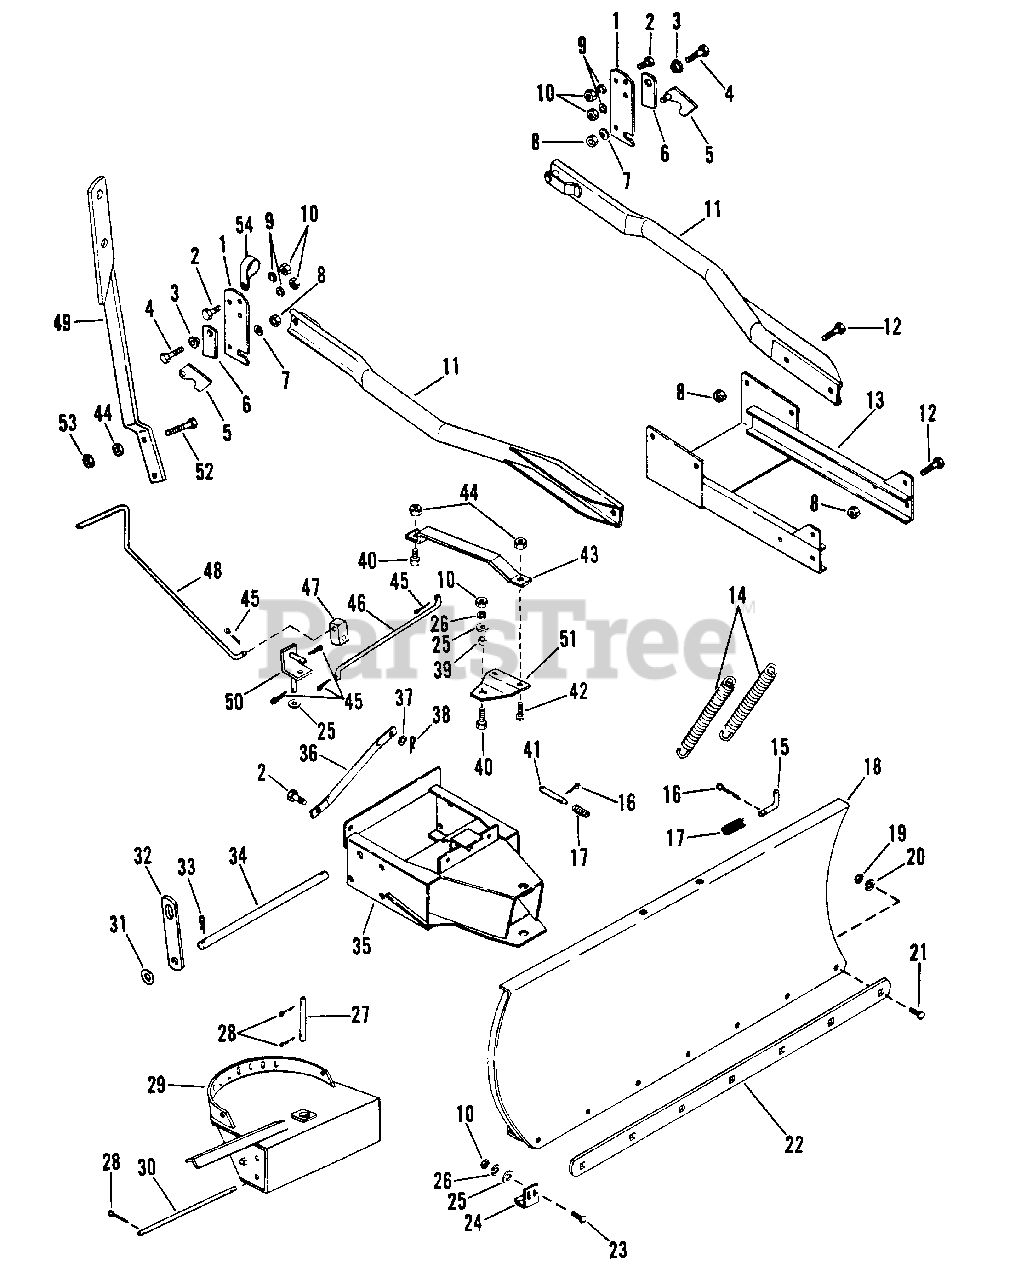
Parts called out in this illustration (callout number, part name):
1	Bracket, Rear Hanger
2	Bolt, Hex 3/8-16x1.00
3	Spacer
4	Bolt, Hex 3/8-16x1.50
5	Latch, R.H.
5	Latch, L.H.
6	Stop, Lock
7	Spring Washer
8	Nut, Lock 3/8-16
9	Washer, Lock 3/8 Reg.
10	Nut, Hex 3/8-16
11	Brace, Rear Attachment
12	Bolt, Hex 3/8-16x.75
13	Cross, Channel
14	Spring, Extension
15	Pin, Jack
16	Pin, Cotter 1/8x1.00
17	Spring, Compression
19	Nut, Hex 5/16-18
20	Washer, Lock 5/16 SP
21	Bolt, Carriage 5/16-18x1.00
22	Plate, Wear
23	Bolt, 3/8-16x1.00 Rd Hd Sq Nk
24	Shoe, Skid
25	Washer, Flat .438x1.00x.083
26	Washer, Lock 3/8 Reg.
27	Pin
28	Pin, Cotter 3/16-1.25
29	Support
30	Rod
31	Washer, Flat .656x1.312x.095
32	Lift, Link
33	Pin, Hair
34	Rod, Pivot
36	Stabilizer
37	Washer 3/8
38	Hair Pin 3/32x1-7/8
40	Bolt, Hex 5/16-18x1.25
41	Pin, Latch
42	Bolt, Carriage 5/16-18x.75
43	Strap
44	Nut, Two Way Lock 5/16-18
45	Pin, Cotter 1/8x3/4
46	Rod
47	Joint, Block
48	Rod
49	Support, Chute Crank
51	Pivot Plate
52	Bolt, Tap 5/16-18x1.50
53	Nut, Lock 5/16-18
54	Clamp
